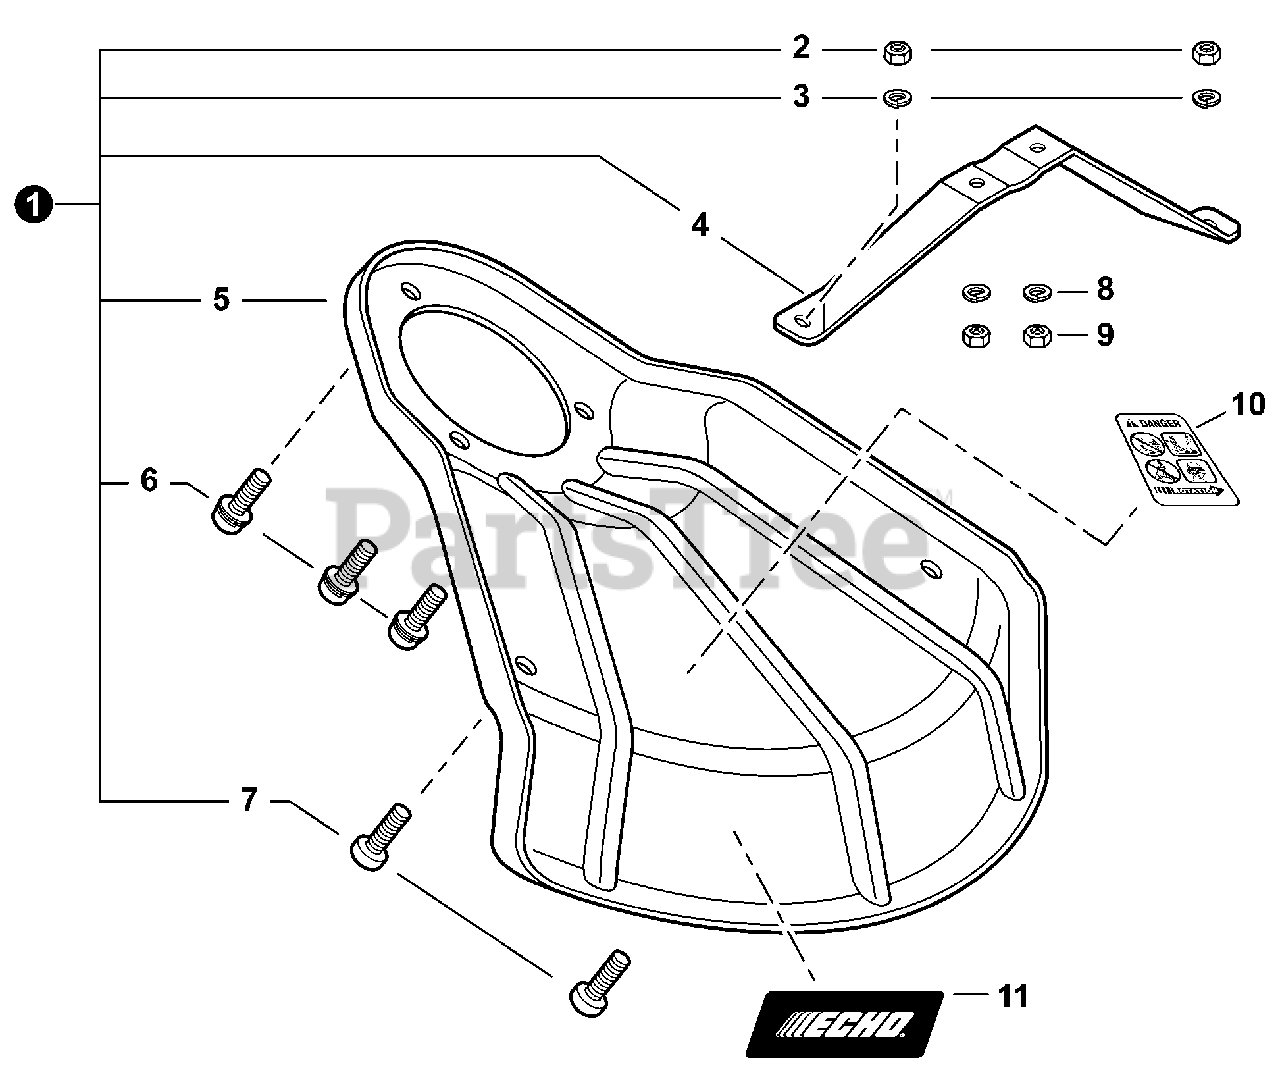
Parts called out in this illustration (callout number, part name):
1	SHIELD ASSY, METAL DEBRIS
3	WASHER, SPRING 5
4	BRACKET, SHIELD MOUNTING
5	SHIELD, METAL DEBRIS 49.5 MM
6	SCREW 5×10
7	SCREW 5×8
8	WASHER, SPRING 5
10	LABEL, DANGER
11	LABEL, ECHO
